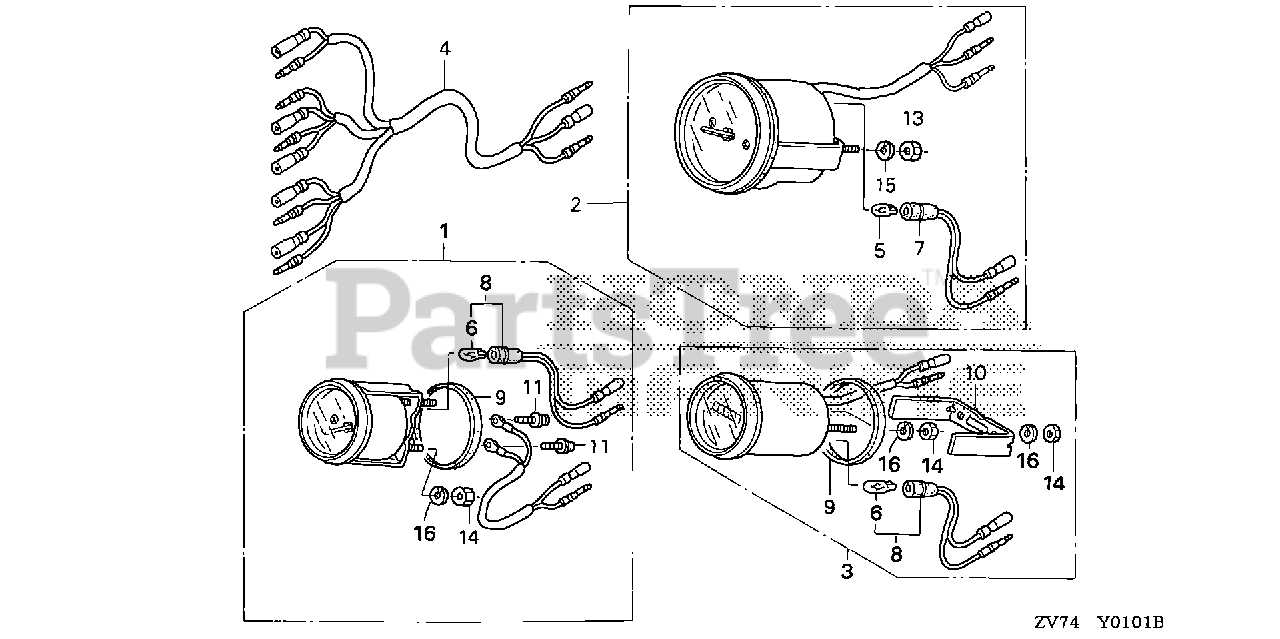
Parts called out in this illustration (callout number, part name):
1	METER KIT, VOLT (B)
1	METER KIT, VOLT
2	METER KIT, TACHO (NOT AVAILABLE)
2	METER KIT, TACHO (B)
3	METER KIT, HOUR (B) (NA USE ALT:39700-ZW5-000ZA)
3	METER KIT, HOUR (NA USE ALT:39700-ZW5-000ZA)
4	HARNESS ASSY., METER (B)
5	BULB, WEDGE BASE (T10) (12V 1.7W) (STANLEY)
6	BULB, WEDGE BASE (12V 1.7W)
7	SOCKET
8	SOCKET
9	GASKET
10	BRACKET
11	SCREW-WASHER (3X22)
13	NUT, HEX. (5MM)
15	WASHER, SPRING (5MM)
16	WASHER, SPRING (4MM)
